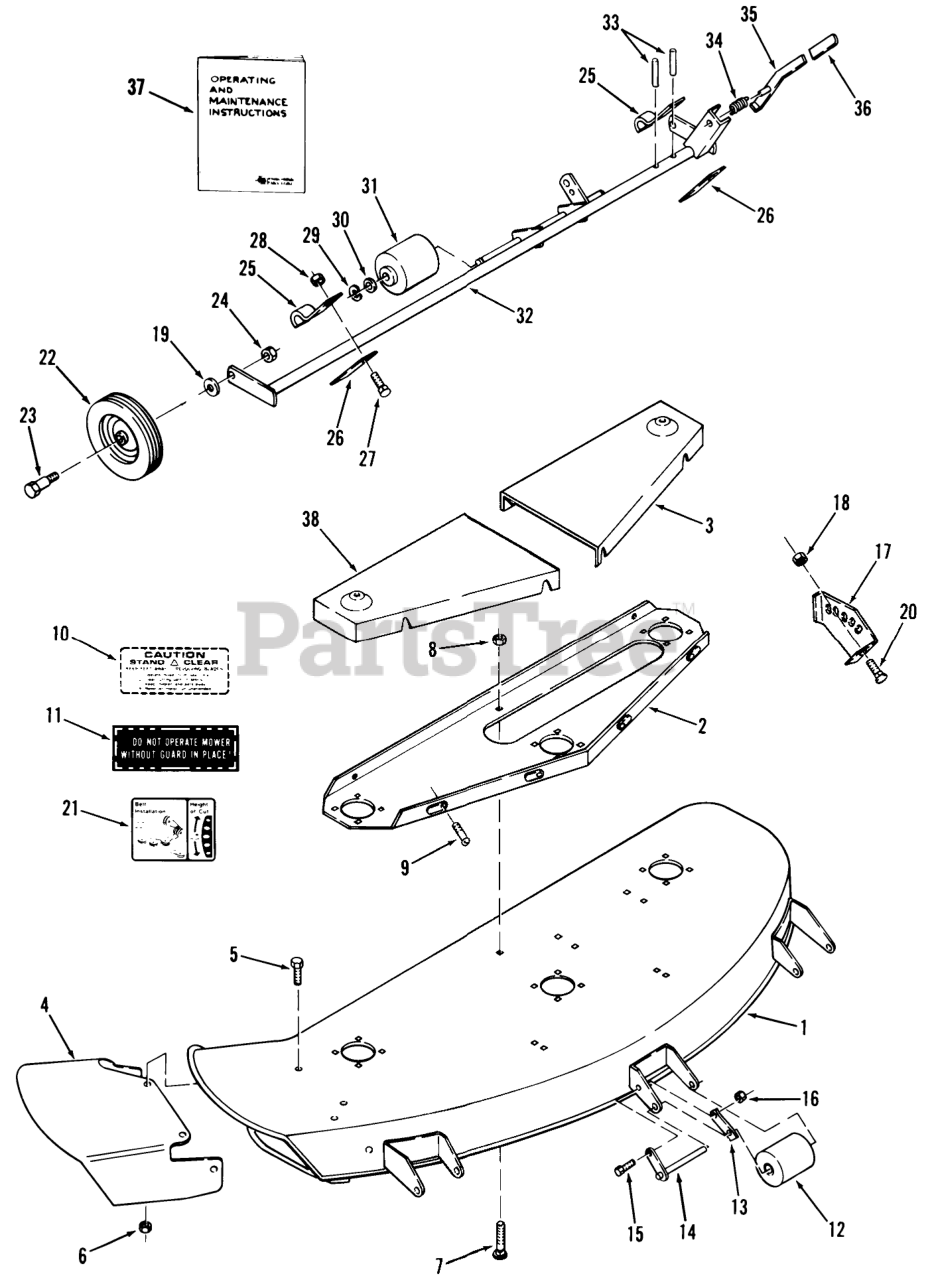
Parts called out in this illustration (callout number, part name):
1	ASSY-48 MOWER DEC R
2	Channel
3	Belt Cover LH
4	Chute Extension
5	Bolt
6	Nut
7	Bolt-Carriage
8	NUT
9	Screw
10	Caution Decal
11	Decal-Caution
12	Roller
13	SPRING ROLLER STOP
14	Roller Shaft
15	H H C S
16	Nut
17	LH QUADRANT R
18	NUT
19	WASHER
20	Bolt
21	Decal, Height Adj. & Belt Diagram
22	Wheel 6 x 1.75 (w/5306 Bushings)
23	BOLT-SHOULDER
24	Nut
25	Machine Bolt
26	Bar
27	Bolt
28	NUT
29	E Ring
30	Washer
31	Roller
32	Gage Wheel Support
33	PIN-SPIROL
34	SPRING-COMPRESSION
35	Lever
37	Operating and Maintenance Instructions
38	Belt Cover RH
